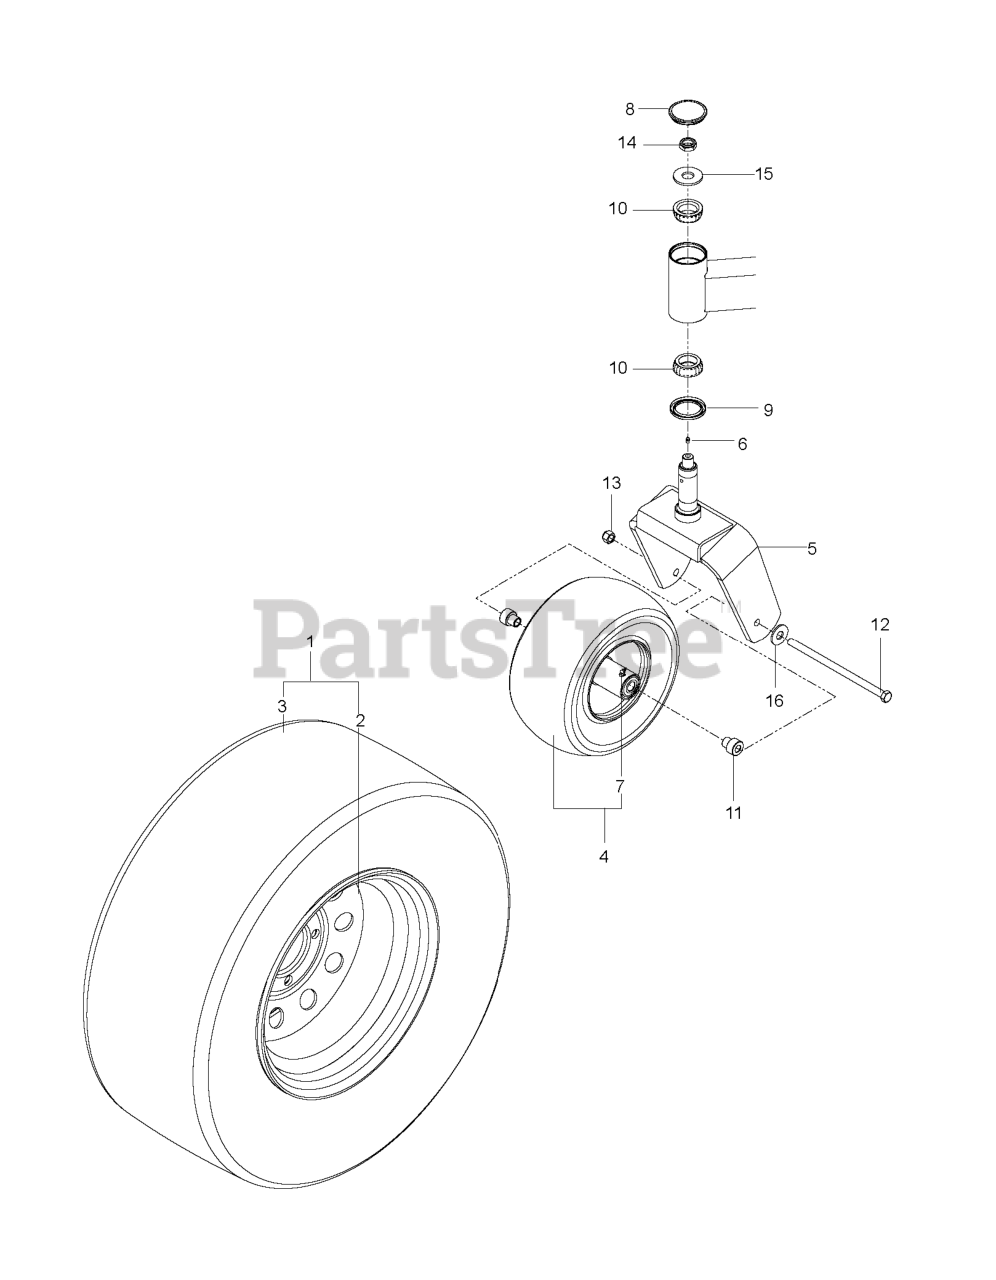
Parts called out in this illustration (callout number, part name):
2	SPRING BRACKET
7	NUT
8	STEERING ROD
9	SPACER
13	BALL BEARING 6004-2RS1
17	CIRCLIP SGH 47
18	BALL-BEARING 6204-2RS
22	RP STEERING CABLE COMPLETE
24	SHAFT
25	RETAINING RING
26	STEERING CHAIN
28	WIRE GUIDE
29	NUT
30	RETAINING RING SGA 25
35	NUT
